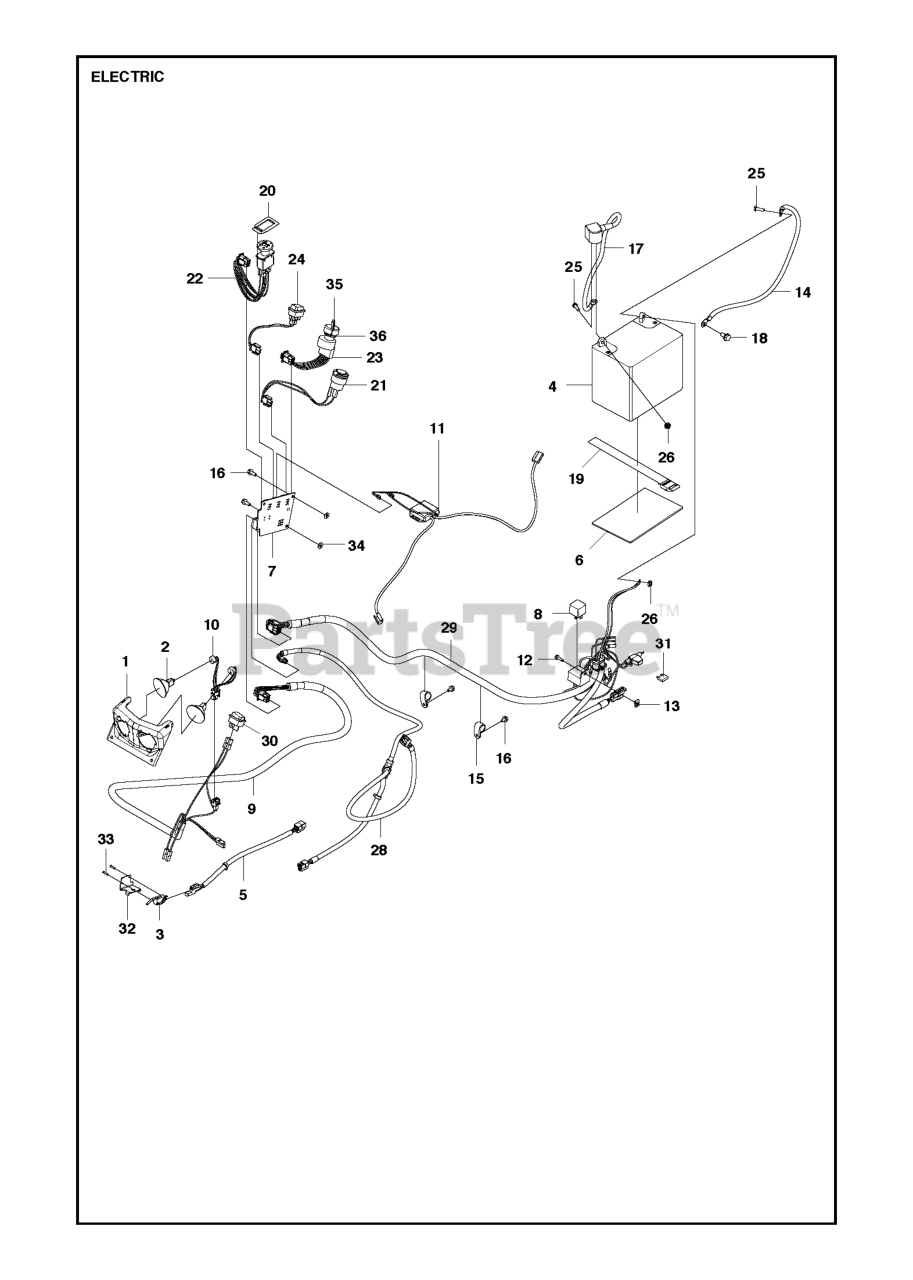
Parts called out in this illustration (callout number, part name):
2	LIGHT
3	MICRO SWITCH
5	WIRING
25	SCREW EHHM
31	FUSE 20AMP
